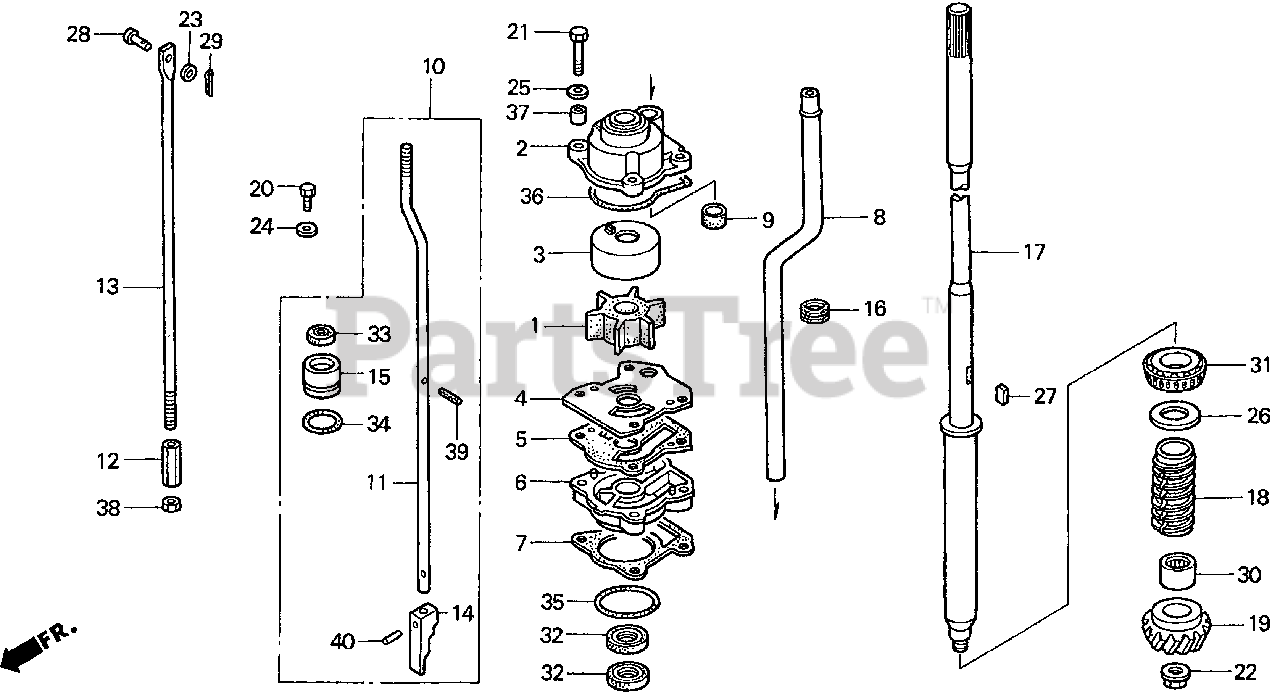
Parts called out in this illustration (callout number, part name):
1	IMPELLER, PUMP
2	HOUSING, IMPELLER
3	LINER, PUMP
4	COVER, IMPELLER
5	GASKET B, IMPELLER
6	HOUSING, WATER PUMP
7	GASKET, WATER PUMP
8	TUBE, WATER (S)
9	RING, WATER TUBE SEAL
10	ROD, SHIFT (S)
11	ROD B, SHIFT (S)
12	JOINT, SHIFT ROD
13	ROD A, SHIFT
14	ROD, PUSH
15	HOLDER, SEAL
16	GROMMET, EXTENSION CASE
17	SHAFT, VERTICAL (S)
18	SLINGER, OIL
20	BOLT, HEX. (6X12)
21	BOLT, HEX. (6X40)
22	NUT, SPECIAL FLANGE (10MM)
23	WASHER, PLAIN (5MM)
24	WASHER, FRICTION
25	WASHER (6MM)
26	SHIM, GEAR (40X46X0.10) (A)
26	SHIM, GEAR (40X46X0.15) (B)
26	SHIM, GEAR (40X46X0.30) (C)
26	SHIM, GEAR (40X46X0.50) (D)
27	KEY, WOODRUFF (5MM)
28	PIN (5X17)
29	PIN, COTTER (1.6MM)
30	BEARING, NEEDLE (7/8X11/8X1)
31	BEARING (25X47X15)
32	SEAL, WATER (17X30X7)
33	SEAL, WATER (6MM)
34	O-RING (20.8X2.4)
35	O-RING (41.7X3.5)
36	O-RING, WATER PUMP
37	COLLAR, IMPELLER HOUSING
38	NUT, HEX. (6MM)
39	PIN, SPRING (2X12)
40	ROLLER (2.5X13.8)
